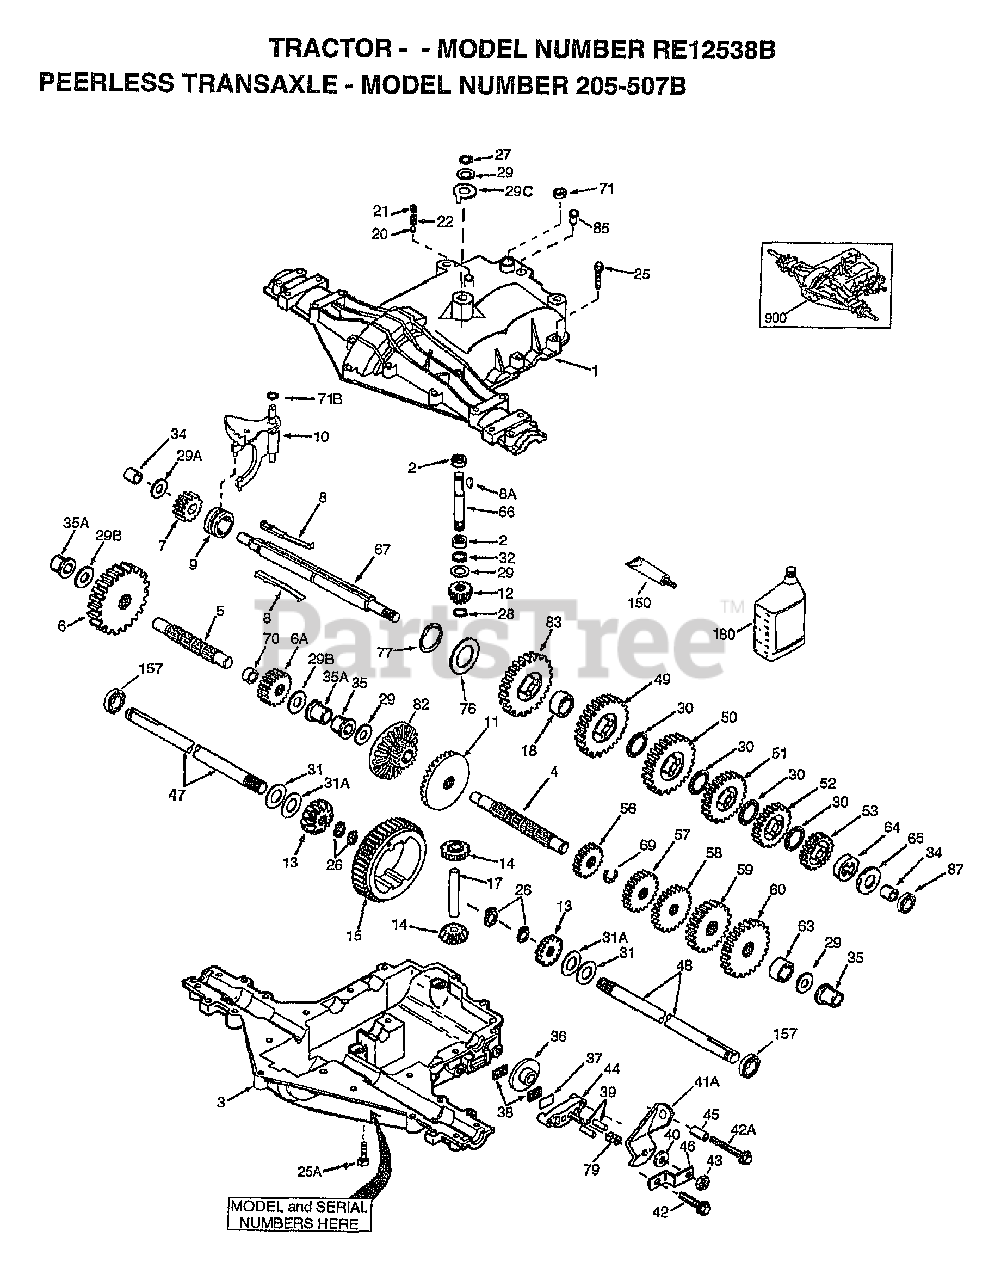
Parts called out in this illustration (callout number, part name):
1	TRANSAXLE COVER
2	NEEDLE BEARING 5/8" ID
3	TRANSAXLE CASE
4	COUNTERSHAFT
5	OUTPUT SHAFT
6	SPUR GEAR (38 TEETH)
6A	SPUR GEAR (15 TEETH)
7	SPUR GEAR (11 TEETH)
8A	KEY, WOODRUFF
9	COLLAR, SHIFTER
10	SHIFT ROD & FORK
11	BEVEL GEAR (30 TEETH)
12	INPUT BEVEL PINION (13TEETH)
13	BEVEL GEAR (13 TEETH)
14	BEVEL PINION (13 TEETH)
15	RING GEAR (43 TEETH)
18	SPACER, NEUTRAL
20	BALL STEEL, 5/16" DIA.
21	SCREW, 3/8-16 X 3/8"
25A	SCREW 1/4-20 X 1-3/8"
26	RING RETAINER
27	RING, RETAINER
28	RETAINING RING
29	WASHER THRUST
29B	WASHER THRUST
30	WASHER THRUST
31A	FLAT WASHER
32	OIL SEAL 5/8"
34	BUSHING 9/16"
35	FLANGED BUSHING 5/8" ID
35A	FLANGED BUSHING 3/4"
37	PLATE BRAKE PAD
41A	BRAKE LEVER
42A	SCREW, 1/4-20 X 2-1/4
43	LOCKNUT 5/16-24
44	HOLDER BRAKE PAD
46	BRKT BRAKE LEVER
49	SPUR GEAR (29 TEETH)
50	SPUR GEAR (23 TEETH)
51	SPUR GEAR (19 TEETH)
52	SPUR GEAR (16 TEETH)
53	SPUR GEAR (15 TEETH)
56	SPUR GEAR (11 TEETH)
57	SPUR GEAR (17 TEETH)
58	SPUR GEAR (21 TEETH)
59	SPUR GEAR (24 TEETH)
60	SPUR GEAR (25 TEETH)
66	INPUT SHAFT
67	SHIFTER & BRAKE SHAFT
69	RETAINING RING
70	SPACER .890
71	SEAL SQUARE CUT
76	WASHER, THRUST
77	INVERTED RETAINING RING
82	BEVEL & SPUR GEAR (30 & 13 TEETH)
83	SPUR GEAR (27 TEETH)
85	OIL FILL PLUG
87	OIL SEAL 9/16"
150	LIQUID GASKET RTV SILICONE
157	OIL SEAL 3/4"
180	GEAR OIL 80W90
